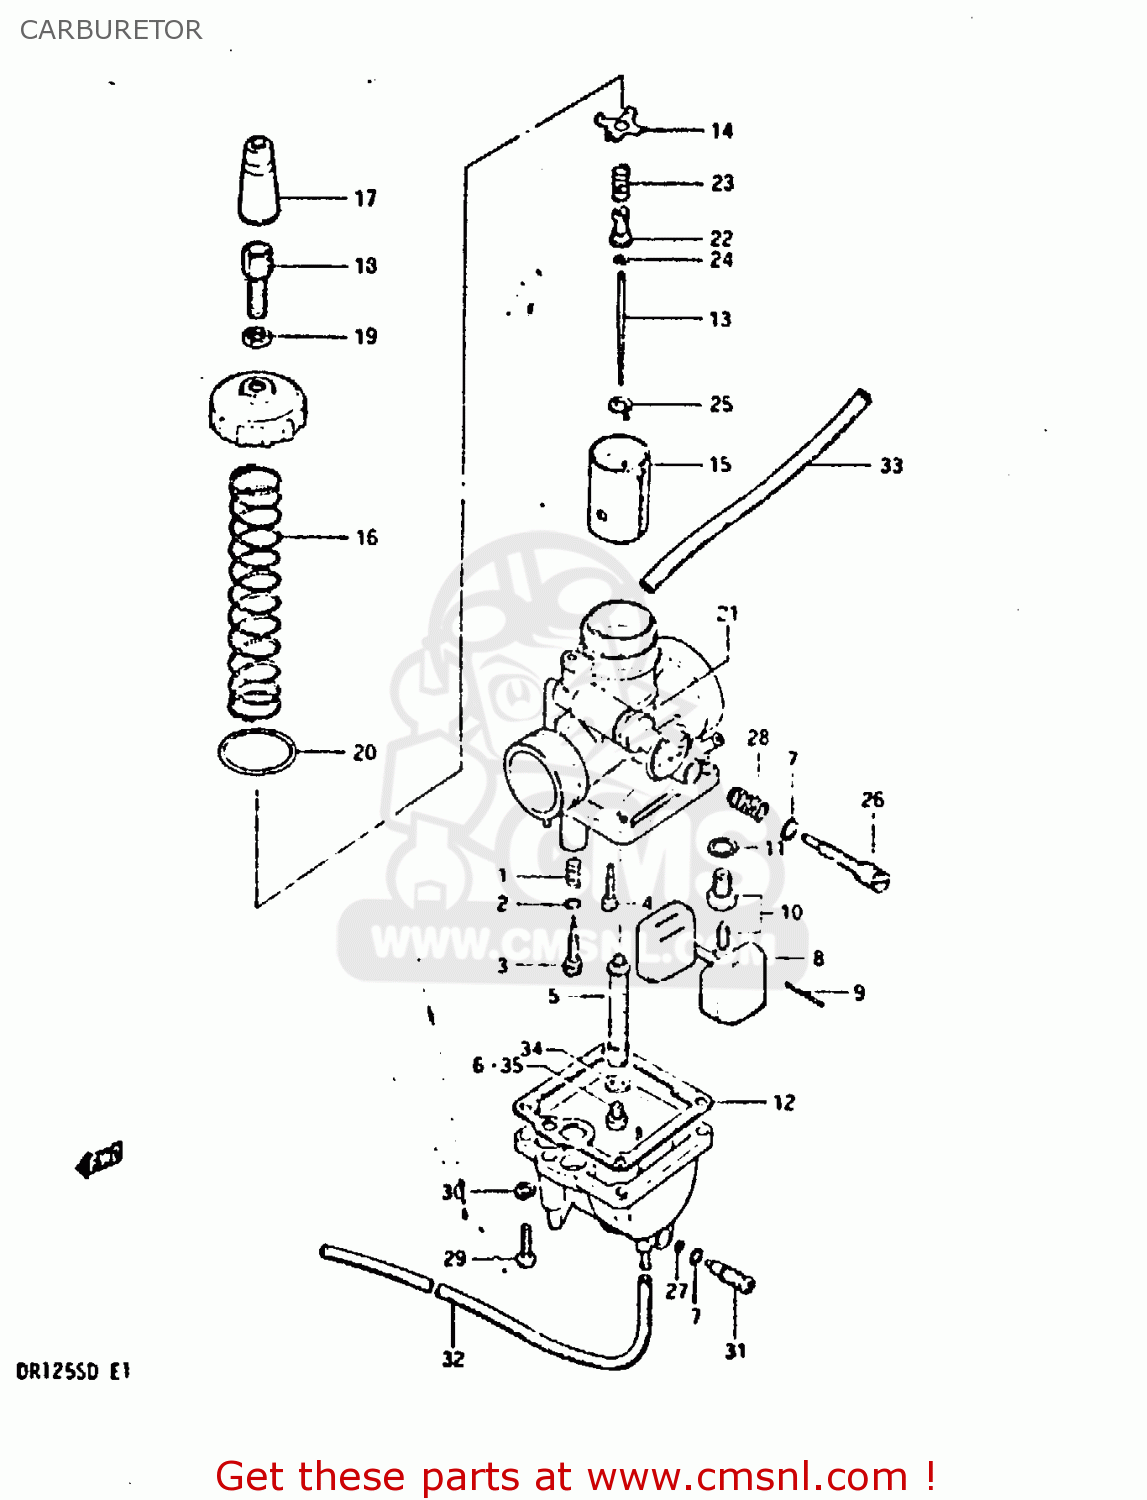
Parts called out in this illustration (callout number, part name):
1	SPRING,THROTTLE ADJUST
2	O-RING
3	SCREW,PILOT AIR
4	JET,PILOT
5	JET,NEEDLE
6	JET,MAIN
7	O-RING
8	FLOAT
9	PIN,FLOAT
10	VALVE ASSY,NEEDLE(ID:2.0)
11	GASKET,NEEDLE VALVE SE
12	GASKET,FLOAT CHAMBER (NAS)
13	NEEDLE JET
14	PLATE,THROTTLE VALVE
15	VALVE,THROTTLE
16	SPRING,THROTTLE VALVE
17	CAP
18	ADJUSTER,CABLE
19	NUT,CABLE ADJUSTER LOCK
20	O-RING,MIXING CHAMBER
21	VALVE ASSEMBLY,STARTER
22	HOLDER,NEEDLE
23	SPRING,NEEDLE JET
24	E-RING
25	RECEIVER,NEEDLE
26	SCREW,THROTTLE STOP
27	O-RING,DRAIN PLUG
28	SPRING,THROTTLE SCREW
29	SCREW
30	LOCK WASHER
31	PLUG,DRAIN
32	HOSE
33	HOSE
34	WASHER,MAIN JET
35	JET,MAIN
